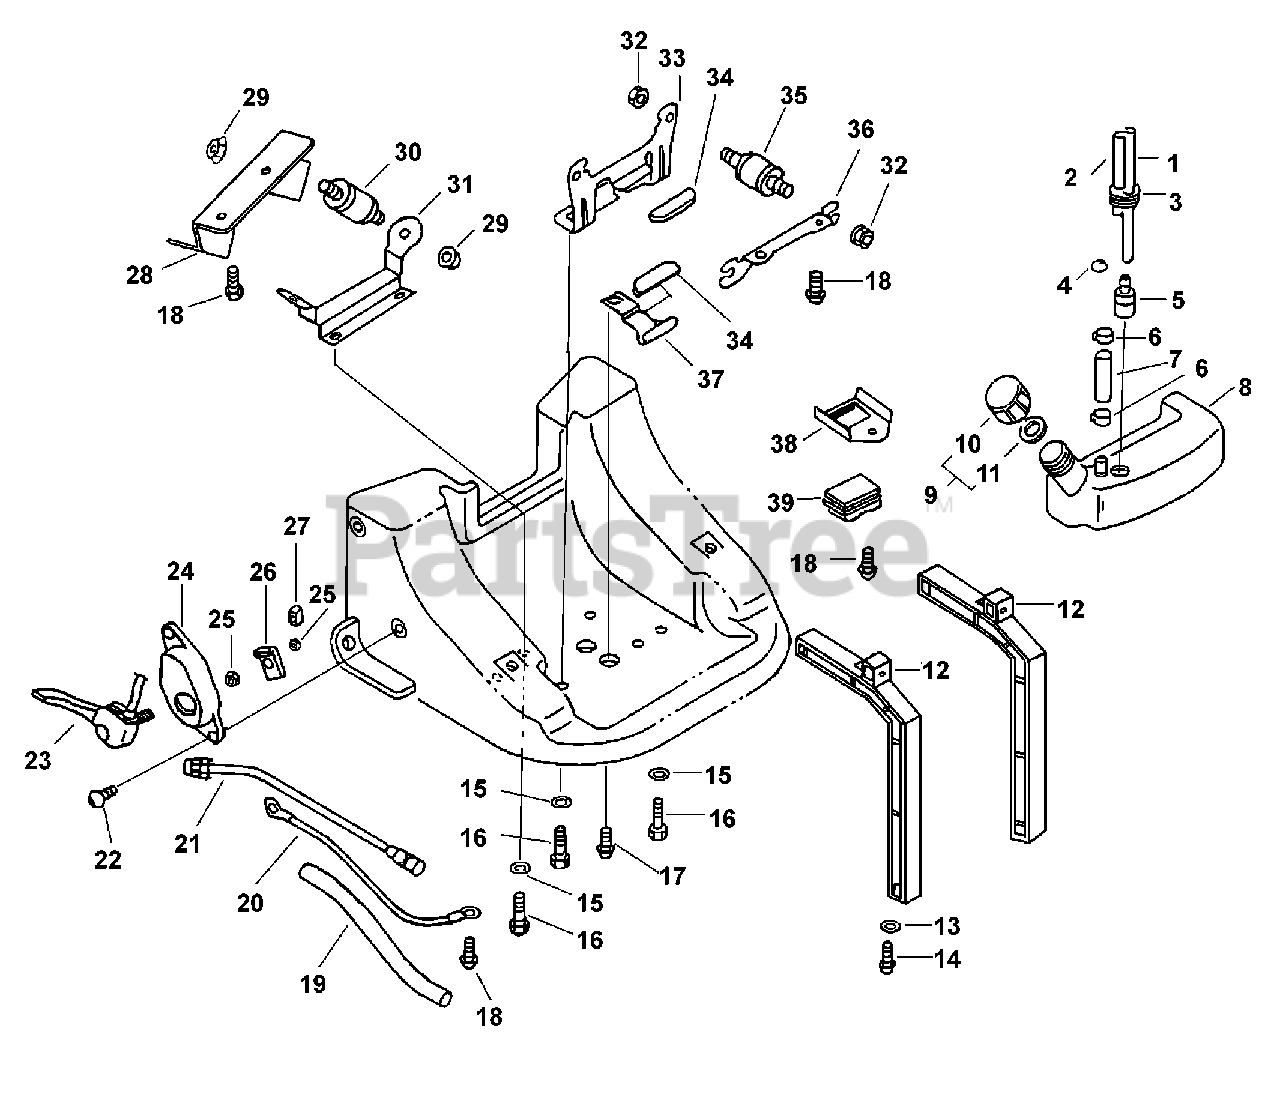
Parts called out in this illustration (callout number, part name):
1	PIPE, FUEL 3×6×200
3	GROMMET, FUEL
4	CLIP 6.5MM
5	FILTER, FUEL
6	CLIP 10.5MM
7	PIPE, FUEL 8×11×70
8	TANK, FUEL
9	CAP ASSY, FUEL
10	CAP, FUEL TANK
11	GASKET, FUEL CAP
12	FRAME, BACKPACK
14	SCREW, TAPPING
16	BOLT 6×16
17	SCREW 6×15
18	SCREW 5×12
19	PROTECTOR, TUBE
21	SWITCH, STOP
22	SCREW 5×20
23	CONTROL, THROTTLE
24	BRACKET, THROTTLE
26	PLATE, FIXED
28	PLATE, ANGLE
29	NUT, FLANGE 6
31	PLATE, ANGLE
32	NUT, FLANGE 5
33	BRACKET, FUEL TANK
34	CUSHION, FUEL TANK
36	BRACKET, ENGINE
37	BRACKET, FUEL TANK
38	PLATE, ANGLE
